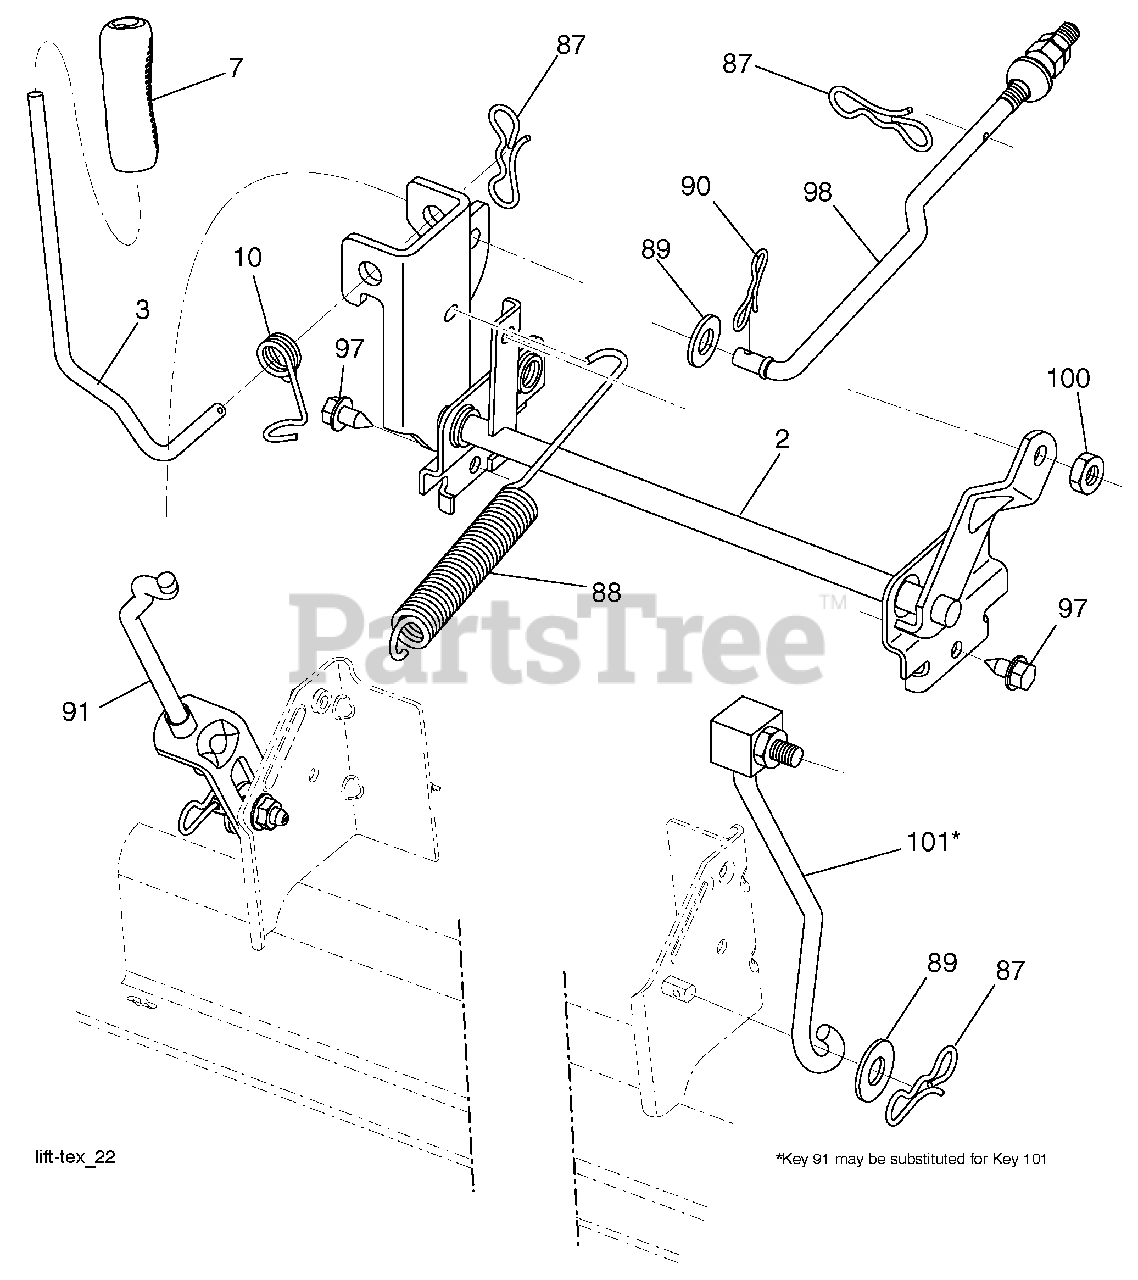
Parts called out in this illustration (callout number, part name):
2	Shaft Asm., Lift
3	Lever Asm., Lift RH
7	Grip, Lever
10	Spring Torsion
87	Pin Cotter 7/16 Bow Tie Lock
88	Spring Lift Assist
89	Washer Clear Zinc
90	Pin Cotter 5/16 Bow Tie Lock
91	Link Asm. Lift Rear
97	Screw 3/8-16 x .75 Smgml Tap/R.Z
98	Link Lift Susp. Front Mower
100	Nut Centerlock 3/8-16 unc
101	Link Asm. Lift Fixed
